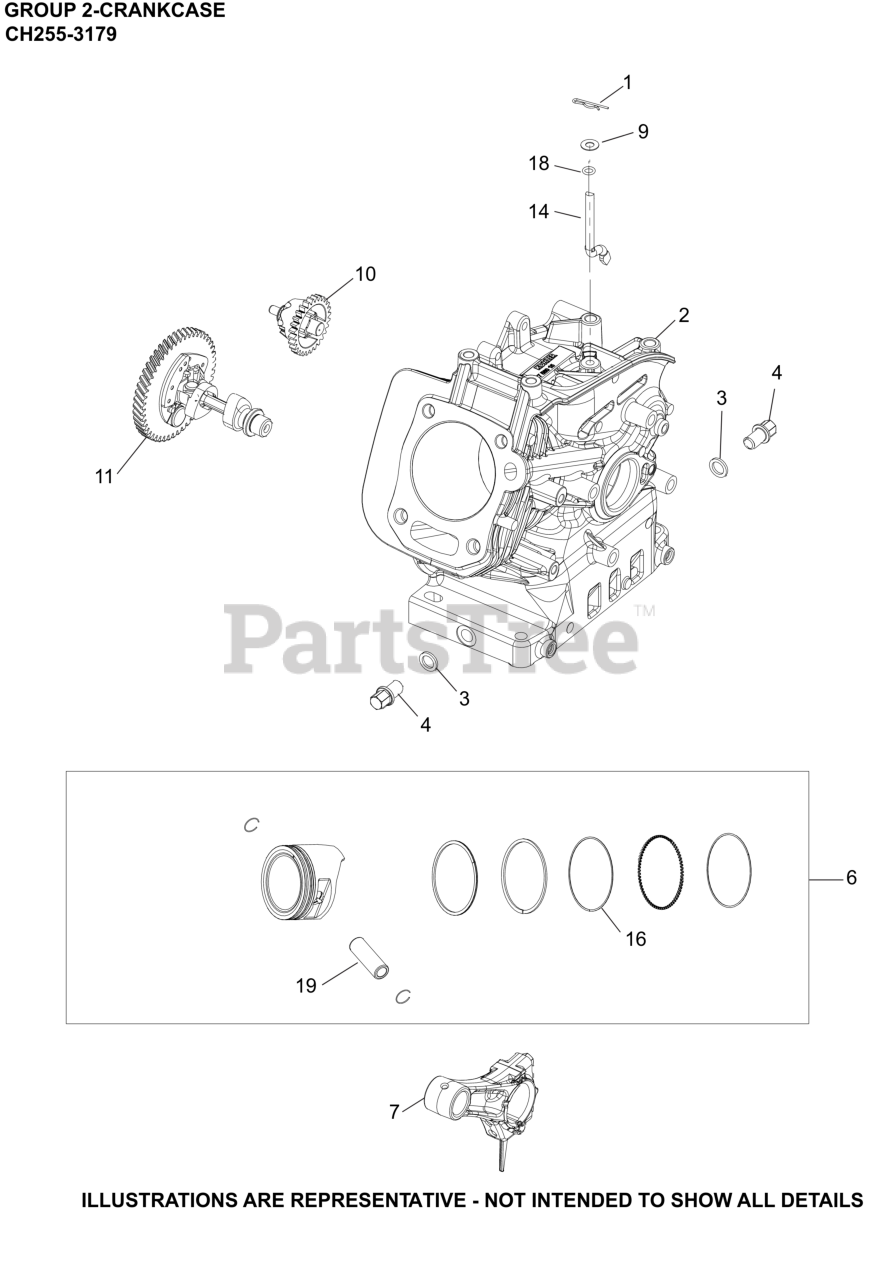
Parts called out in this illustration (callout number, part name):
1	CLIP, GOVERNOR SHAFT
2	CRANKCASE
3	WASHER, DRAIN PLUG
4	KIT, DRAIN PLUG
6	KIT, PISTON (STD)
7	ROD, CONNECTING ASSEMBLY
9	WASHER, FLAT (DIA 13mm O.D.)
10	GOVERNOR ASSEMBLY
14	SHAFT, GOVERNOR CROSS
19	PIN, PISTON
